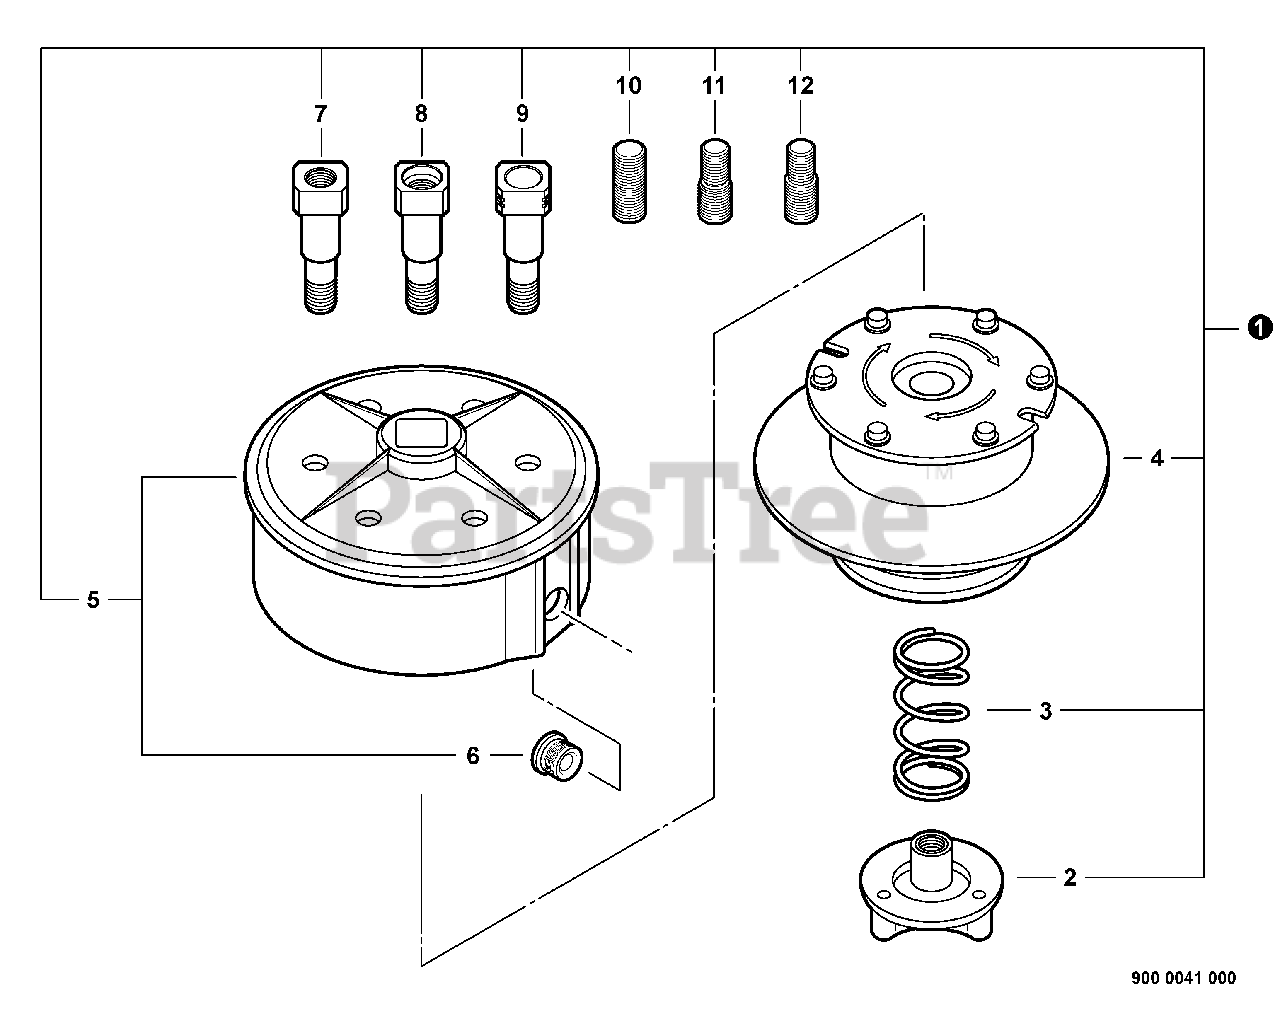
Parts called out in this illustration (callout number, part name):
1	HIGH CAPACITY MANUAL TRIMMER HEAD
2	WINGNUT
5	SPOOL COVER ASSY
7	ARBOR - LEFT HAND
8	ARBOR - LEFT HAND
9	ARBOR - LEFT HAND
10	STUD - BLACK -- LEFT HAND
11	STUD - GOLD -- LEFT HAND
12	STUD - SILVER -- LEFT HAND
